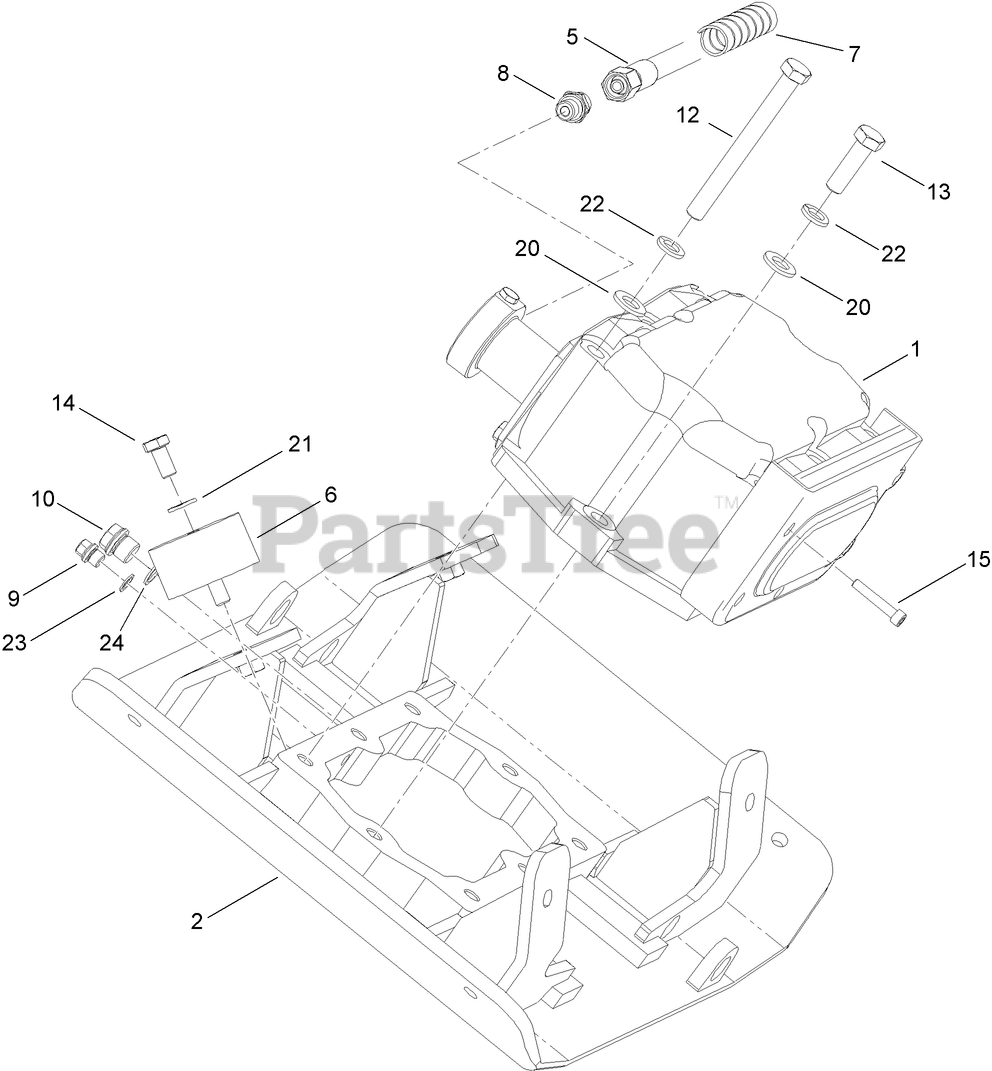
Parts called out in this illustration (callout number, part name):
1	VIBRATORY ASM
2	PLATE-BED
5	HOSE-HYD
6	MOUNT-RUBBER
7	COVER-HOSE
8	SOCKET
14	SCREW-HH
20	WASHER
21	WASHER
22	WASHER
